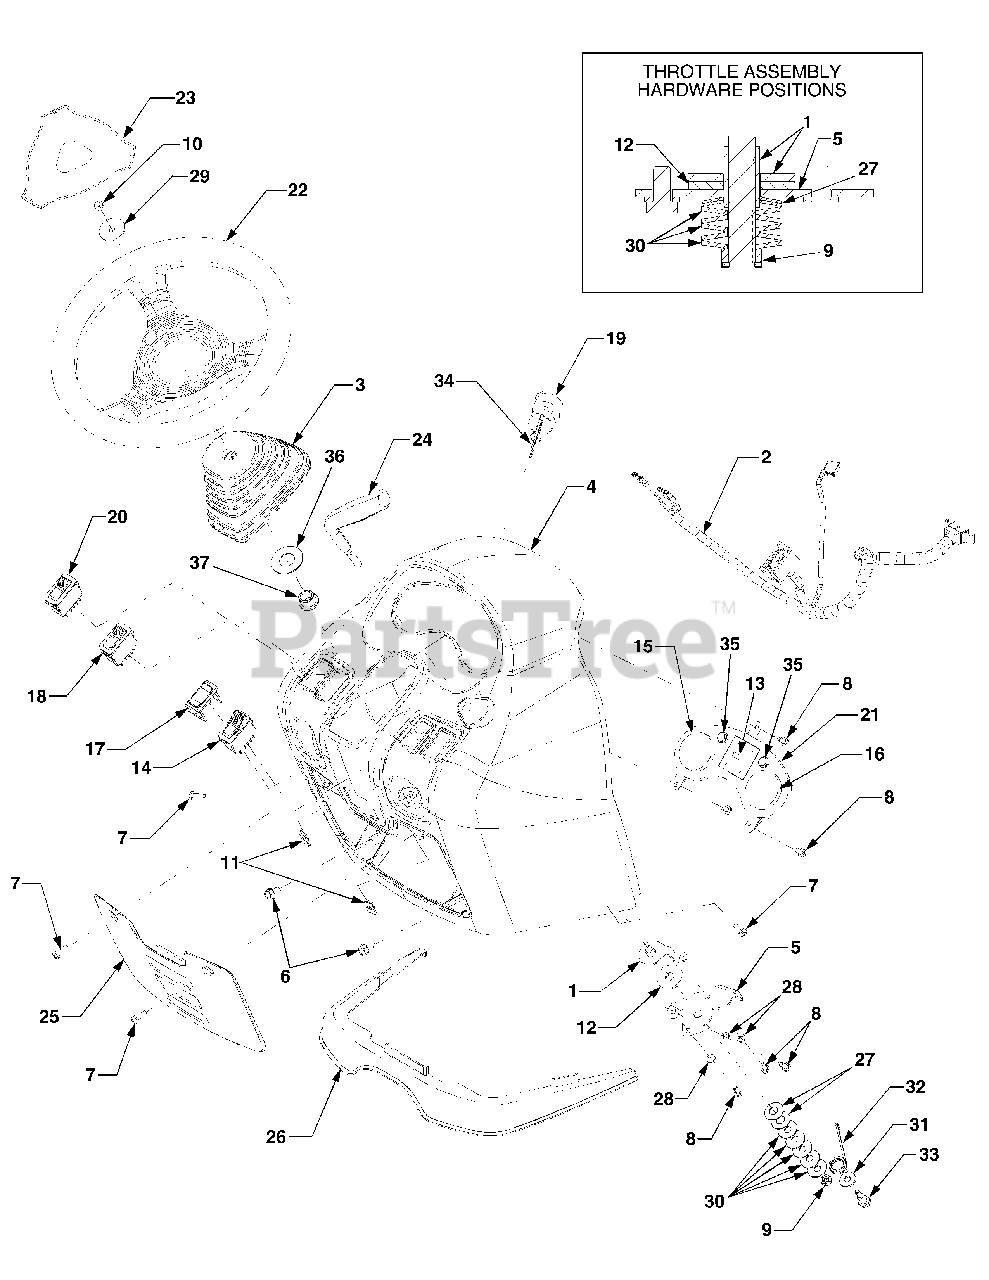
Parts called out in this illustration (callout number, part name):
1	Bracket, Throttle Cable
2	Wire Harness, Dash
3	Boot, Steering Shaft
4	Dash
5	Bracket, Throttle Mtg.
6	Screw, Hex Wash. Hd. Tapp 5/16-18 x .625
7	Screw, Pan Hd., 1/4-20 x .75
8	Screw, Hex Cap, 1/4-20 x .5 GR5
9	Nut, Hex Insert Jam Lock, 3/8-24
10	Nut, Hex Lock, 5/16-24
11	Nut, Speed, 1/4-20
12	Washer, Friction, .515 x 1.5 x .12
13	Meter, Hour/Indicator
14	Switch, PTO
15	Gauge, Fuel
16	Gauge, RPM
18	Switch, Headlight
19	Switch, Ignition
20	Switch, Hazard
21	Panel, Meter
22	Steering Wheel, Soft Grip
23	Cover, Steering Wheel
24	Handle, Throttle
25	Panel, Dash Insert
26	Extension, Dash
27	Washer, Belleville, .51 x 1.14 x .04
28	Washer, Lock, 1/4
29	Washer, Flat, .344 x 1.5 x .1
30	Washer, Belleville, .39 x 1.13 x .062
31	Washer, Flat, .38 x .93 x .110 Hdn
32	Spring, Torsion
33	Screw, Shoulder, .374 x .56
34	Key Set, Ingition
35	Lamp, Yellow Panel
36	Washer, Flat, .885 x1.85 x .06
37	Bearing, Flange, .63 ID x .62 LG .
